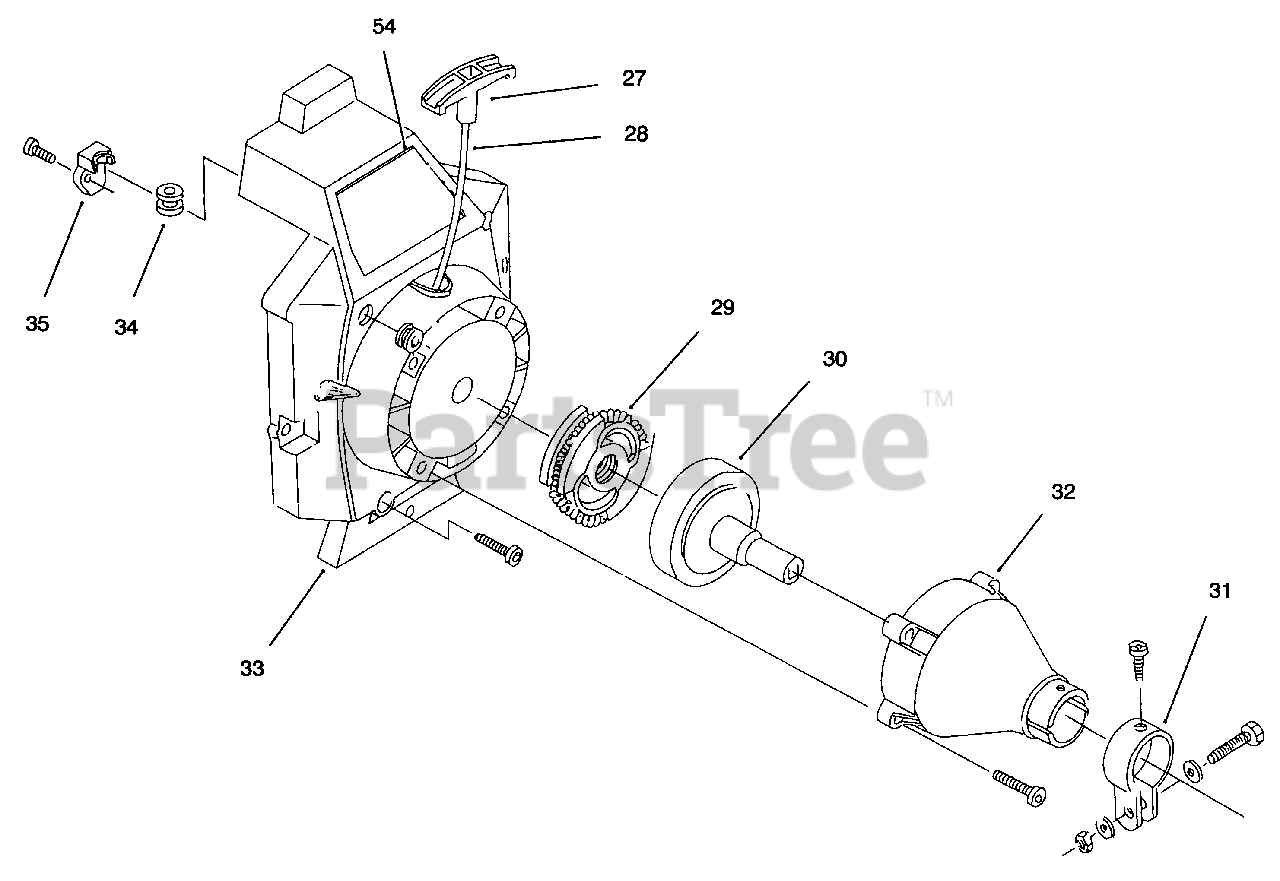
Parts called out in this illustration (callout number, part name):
27	Pull Handle
28	Starter Rope
29	Clutch Rotor Asm.
30	Clutch Drum Asm.
31	Clamp Asm.
32	Clutch Housing Asm.
33	Starter Housing Asm.
34	Rope Guide
35	Pulley Retainer
54	Decal-Toro
